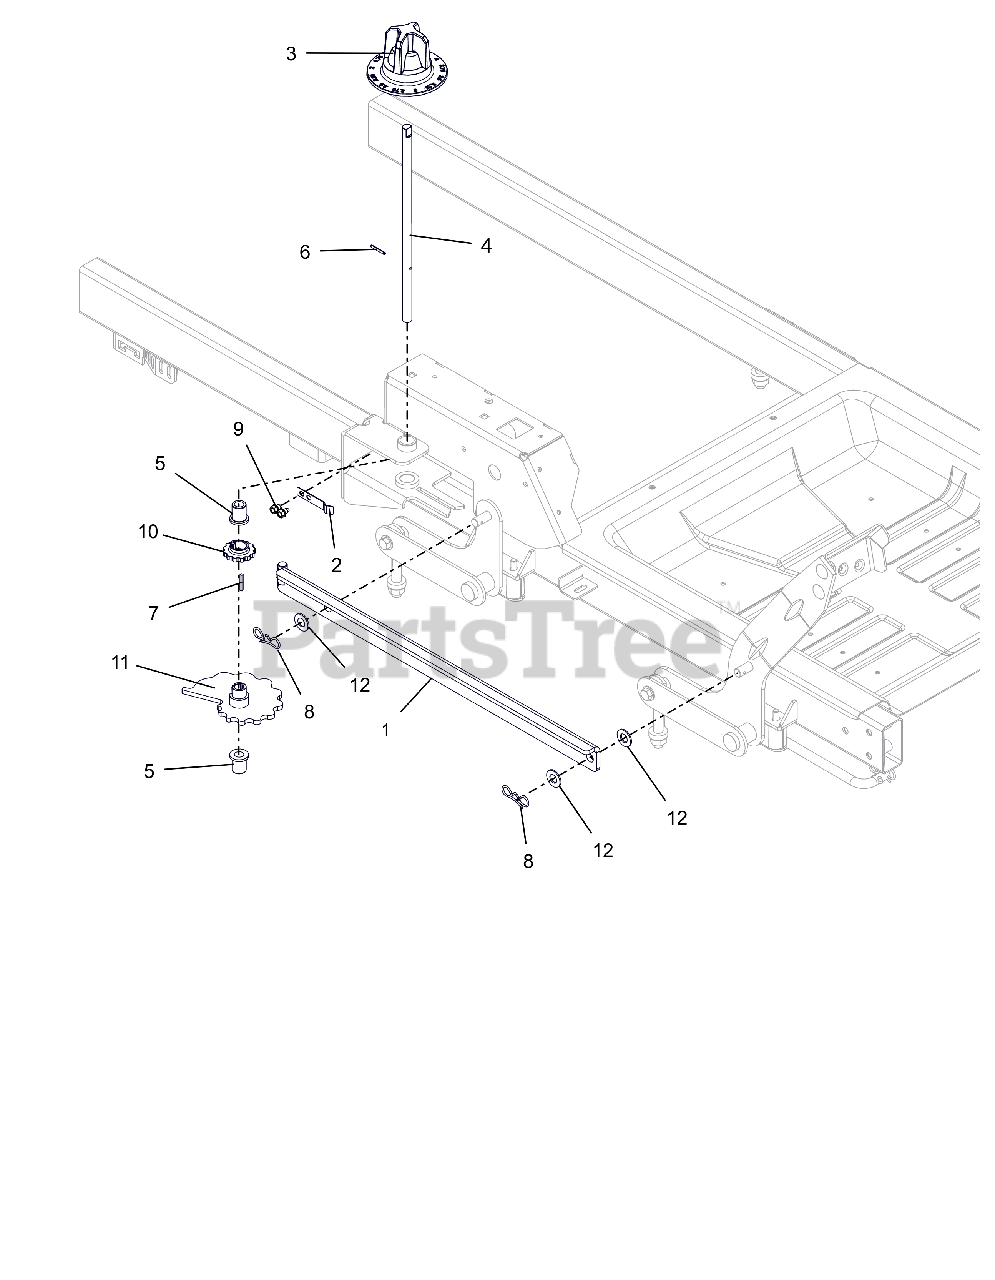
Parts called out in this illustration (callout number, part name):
1	WLDMT, HOC LINK
2	ARM, HOC DETENT
3	KNOB, HOC DIAL
4	SHAFT, HOC CAM IKON
5	BSHG-FLG, .503X.750X.875X1.00
6	PIN-ROLL .125X1.00
7	KEY, 1/8 X 1/8 X 1.0
8	PIN,BOW TIE LOCKING .091X1.875
9	SCR,TAP .25-20X.375 HWH TR ZCC
10	GEAR, HOC INDEX
11	WLDMT, HOC CAM
12	WSHR-FL-NYL .518X1.000X.080
